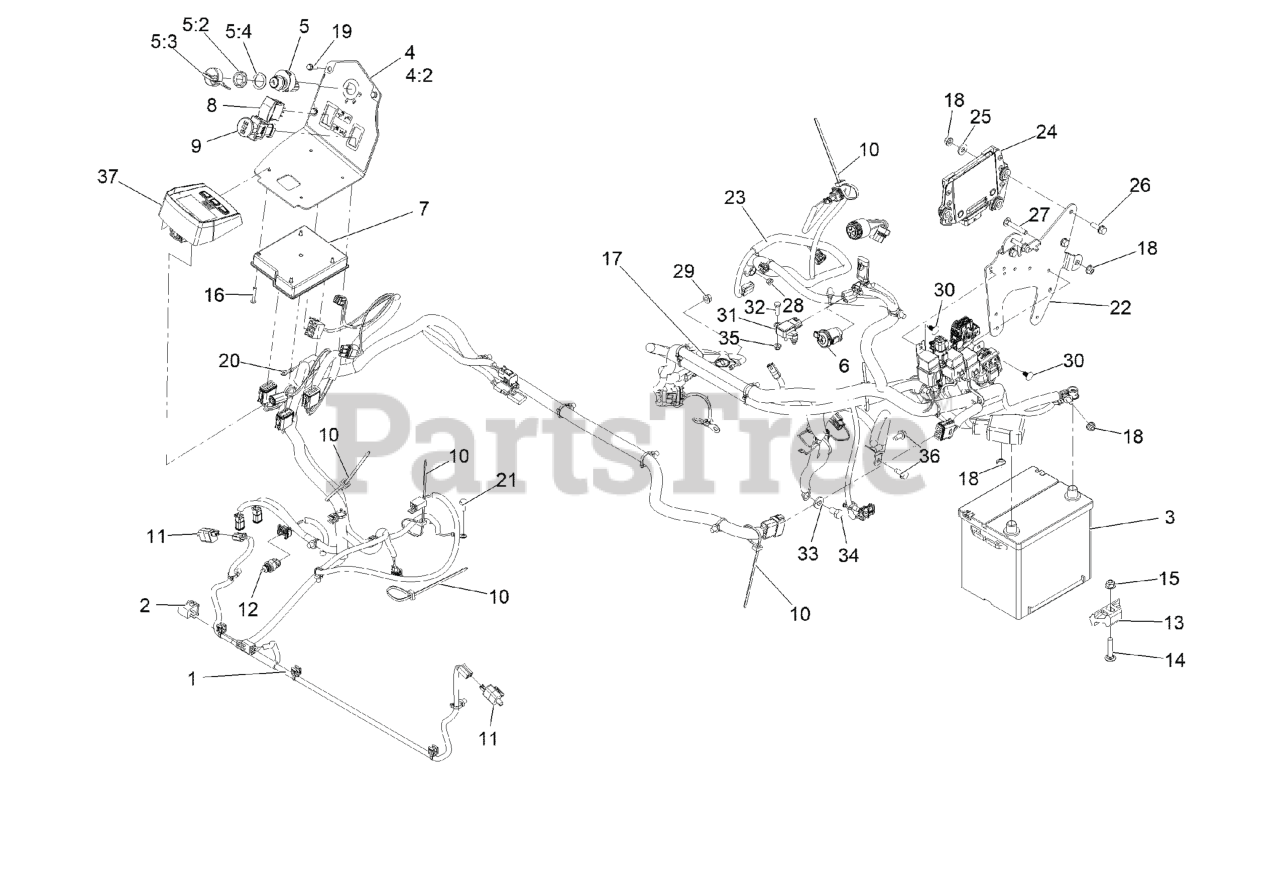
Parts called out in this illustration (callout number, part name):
1	HARNESS-WIRE
2	SWITCH-BAIL
3	Battery-Dry
4	Console ASM
4:2	DECAL-CONTROL PANEL
5	IGNITION SWITCH ASM
5:2	NUT-MOUNTING
5:3	IGNITION KEY SET
5:4	WASHER-BACKUP
6	PORT-POWER, 12V
7	Module-Mcu
9	SWITCH-PTO, SEALED
10	TIE-CABLE
12	SENSOR-TEMPERATURE
13	RETAINER-BATTERY
14	SCREW-CARR
15	NUT-HF, NI
16	SCREW-PPH
17	CABLE-BATTERY
18	NUT-HF, NI
19	SCREW-HWH
20	HARNESS-WIRE, JUMPER
21	BOLT
22	BRACKET-MOUNT, ECU
23	HARNESS-WIRE
24	ECU ASM-SERVICE
25	WASHER-FLAT
26	SCREW-HHF
27	BOLT-CARR
30	PLUG-PLASTIC
31	SENSOR-ATM
32	SCREW-HH
33	WASHER-BELLEVILLE
34	SCREW-HH
36	Screw-HWH 5/16-18 X 3/4 Tf
37	MODULE, LDU
